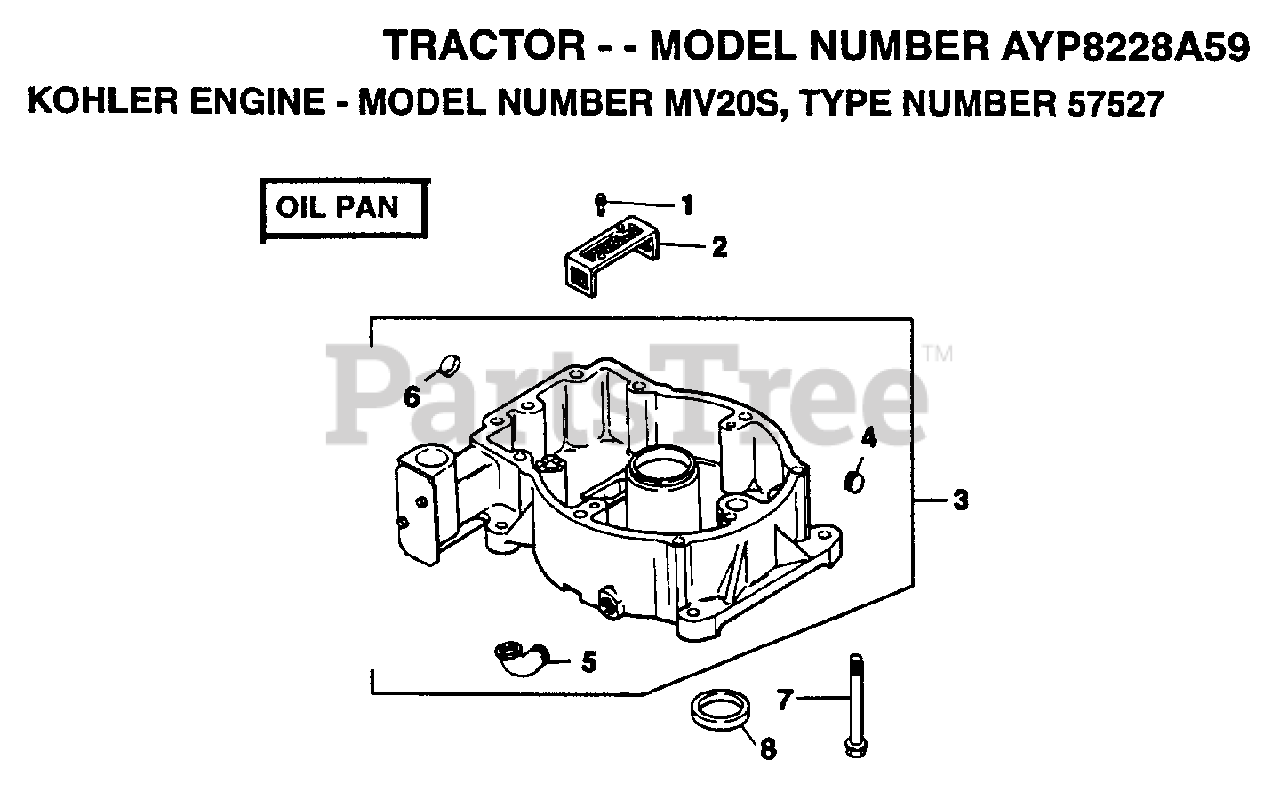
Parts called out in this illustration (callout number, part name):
1	SCREW
4	PLUG
5	ELBOW, STREET
6	PLUG, 1/4
